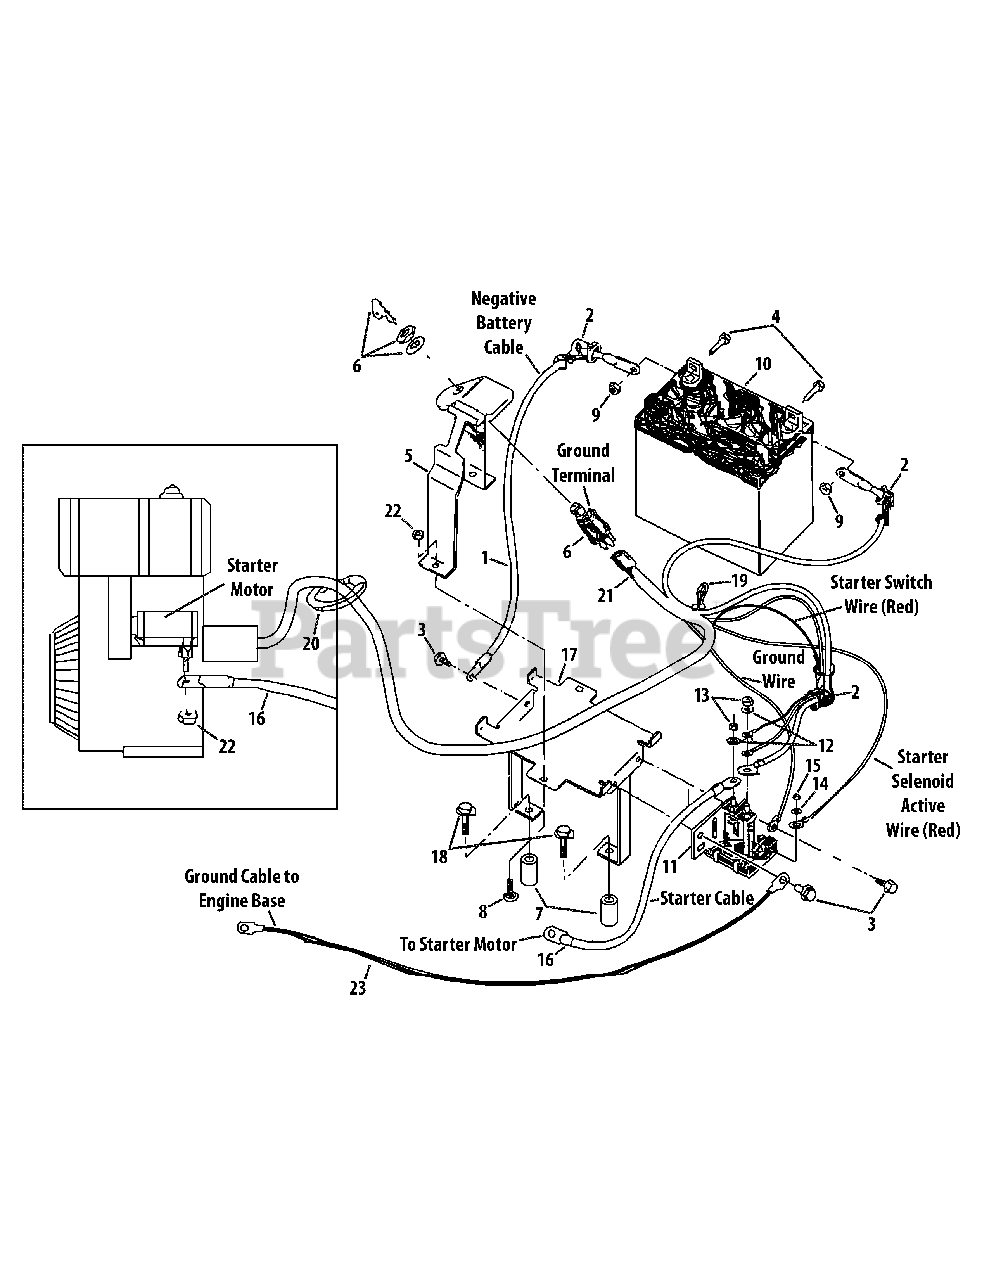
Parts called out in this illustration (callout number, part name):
1	Battery Cable
2	Terminal Insulating Boot
3	TT-Screw, 1/4"-2 x 1/2"
4	Hex Bolt, 1/4"-20 x 5/8"
5	Battery Hold-down Clamp
6	Key Switch (Incl. 2 Keys)
8	Carriage Bolt, 1/4"-20 x 1-1/4"
9	Hex Nut, 1/4"-20
10	12-Volt Battery
11	Starter Solenoid
12	Lockwasher, 5/16"
13	Hex Nut, 5/16"-24
14	External Tooth Lockwasher
15	Hex Nut, #10-32
16	Battery Cable
17	Battery Bracket
18	Hex Head Screw, 3/8"-16 x 2.75"
19	Plastic Tie
20	Plastic Tie
21	Wire Harness & Connecting Terminal Assembly
22	Flangelock Nut, 1/4"-20
23	Ground Cable
